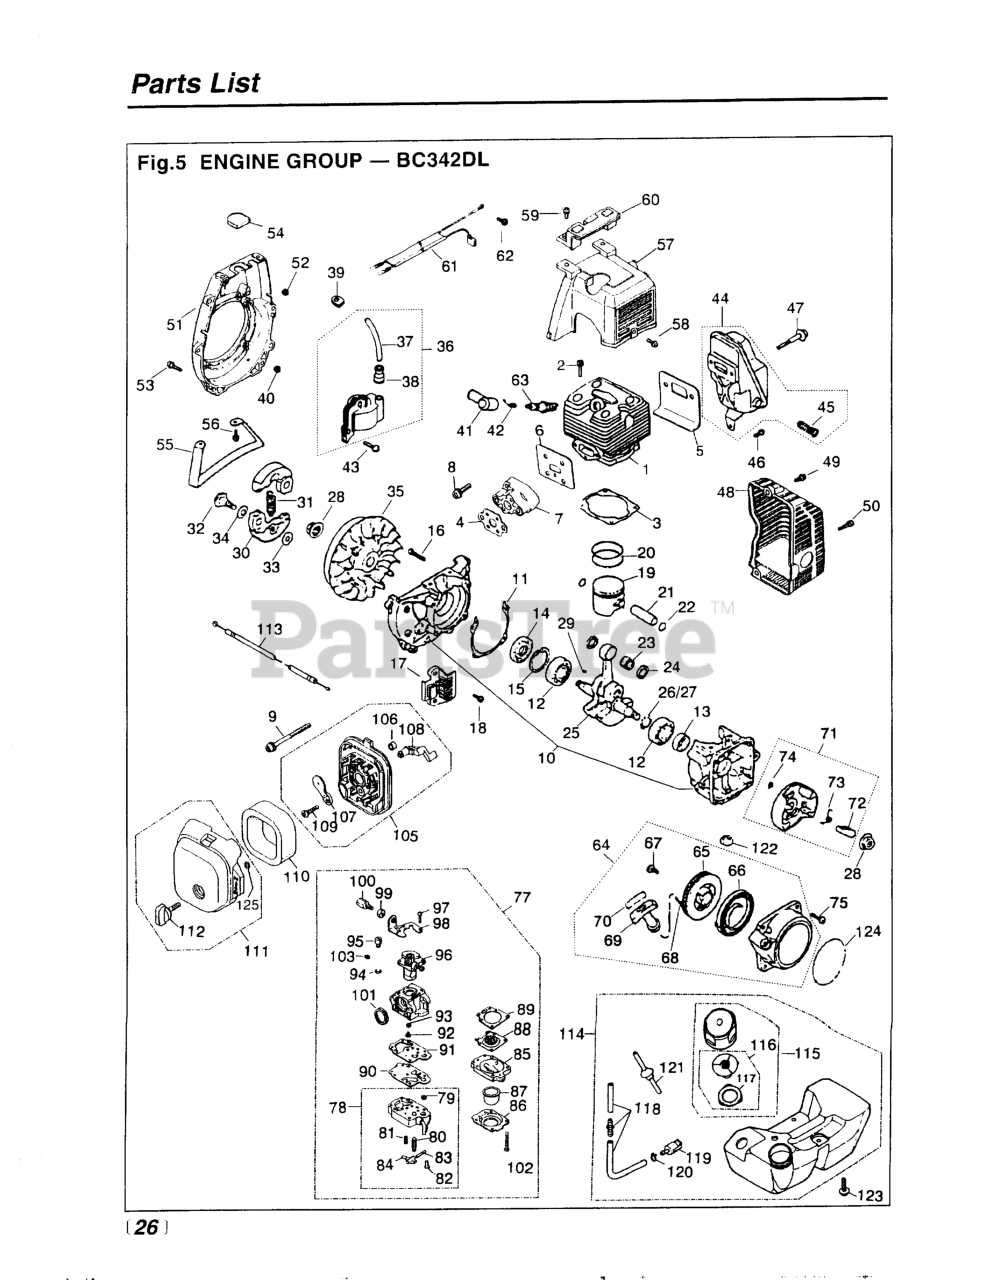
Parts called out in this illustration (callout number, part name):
1	CYLINDER (RPLS -12111)
2	BOLT M5 x 20 (RPLS -12280)
3	GASKET
8	SCREW, M5 x 25
9	SCREW, M5 X 55
10	CRANKCASE (RPLS -21101)
13	SEAL, OIL (RPLS 1100-21210)
14	SEAL, OIL (RPLS 1200-21220)
15	RING, SNAP, M32 x 1.2
16	BOLT, M5 X 30
17	GUARD (RPLS-21310)
18	SCREW,M5 X 14 (RPLS 1400-15510
19	PISTON (RPLS 1650-41111)
20	RING, PISTON
21	PIN
22	RING, SNAP
23	BEARING
24	WASHER (RPLS 3310-41341)
25	CRANKSHAFT CO
26	SHIM (NO LONGER AVAILABLE)
29	KEY
30	SHOE, CLUTCH (RPLS -51110)
31	SPRING, CLUTCH
32	SCREW
33	WASHER
34	WASHER (USE -51241)
36	COIL ASSEMBLY
38	CAP
39	GROMMET
42	SPRING
43	SCREW, M5X20 (RPLS.1400-75510)
44	MUFFLER ASSEMBLY
45	ARRESTER
46	SCREW, M5 X 12
48	COVER, MUFFLER
49	BOLT M5 x 20 (RPLS -12280)
50	BOLT
51	COVER, FAN
53	BOLT M5 x 20 (RPLS -12280)
56	BOLT (REPLACES 01252-30514)
57	COVER, CYLINDER (RPLS-32112)
58	SCREW, M5 X 12
59	SCREW, M5X20 (RPLS.1400-75510)
60	HEAD GUARD
61	CORD COMP
62	SCREW, M5 X 12
64	RECOIL ASSEMBLY
65	REEL
66	SPRING, SPIRAL
67	SCREW (RPLS -75150)
69	KNOB
71	PULLEY ASSEMBLY
72	RATCHET
73	SPRING, RETURN
74	E-RING
75	SCREW, M5X20 (RPLS.1400-75510)
77	CARBURETOR ASSEMBLY (WYJ-118)
78	BODY, PUMP
80	VALVE, INLET
81	SPRING, METERING LEVER
82	SCREW, METERING LEVER PIN
83	PIN, METERING LEVER
84	LEVER
85	BODY, PURGE
86	COVER, PUMP
87	PUMP, PRIMING
88	DIAPHRAGM (USE 4810-81260)
89	GASKET, DIAPHRAGM
90	DIAPHRAGM
91	GASKET, PUMP
92	JET
93	RING, O
94	RING
95	SWIVEL
96	VALVE ASSY
97	SCREW
99	NUT, CABLE ADJUSTER
100	SCREW, CABLE ADJUSTER
101	RING, PACKING
102	SCREW
103	WASHER
105	BODY-A (RPLS -82101)
106	SLEEVE
107	PLATE, CHOKE (RPLS-82130)
108	LEVER, CHOKE
109	SCREW (REPLACES 50030272)
110	ELEMENT
112	KNOB (RPLS -82220)
113	CABLE COMP (RPLS 1633-83100)
116	VALVE COMPLETE
117	PACKING (RPLS -85321)
118	PIPE (RPLS 1601-85403)
119	FILTER ASSY
120	CLIP (REPLACES 2841-31280)
121	PIPE (RPLS 1601-85701)
122	WASHER
123	SCREW, M5 X 22
124	LABEL BC342DL (RPLCS. -75411)
125	RING
